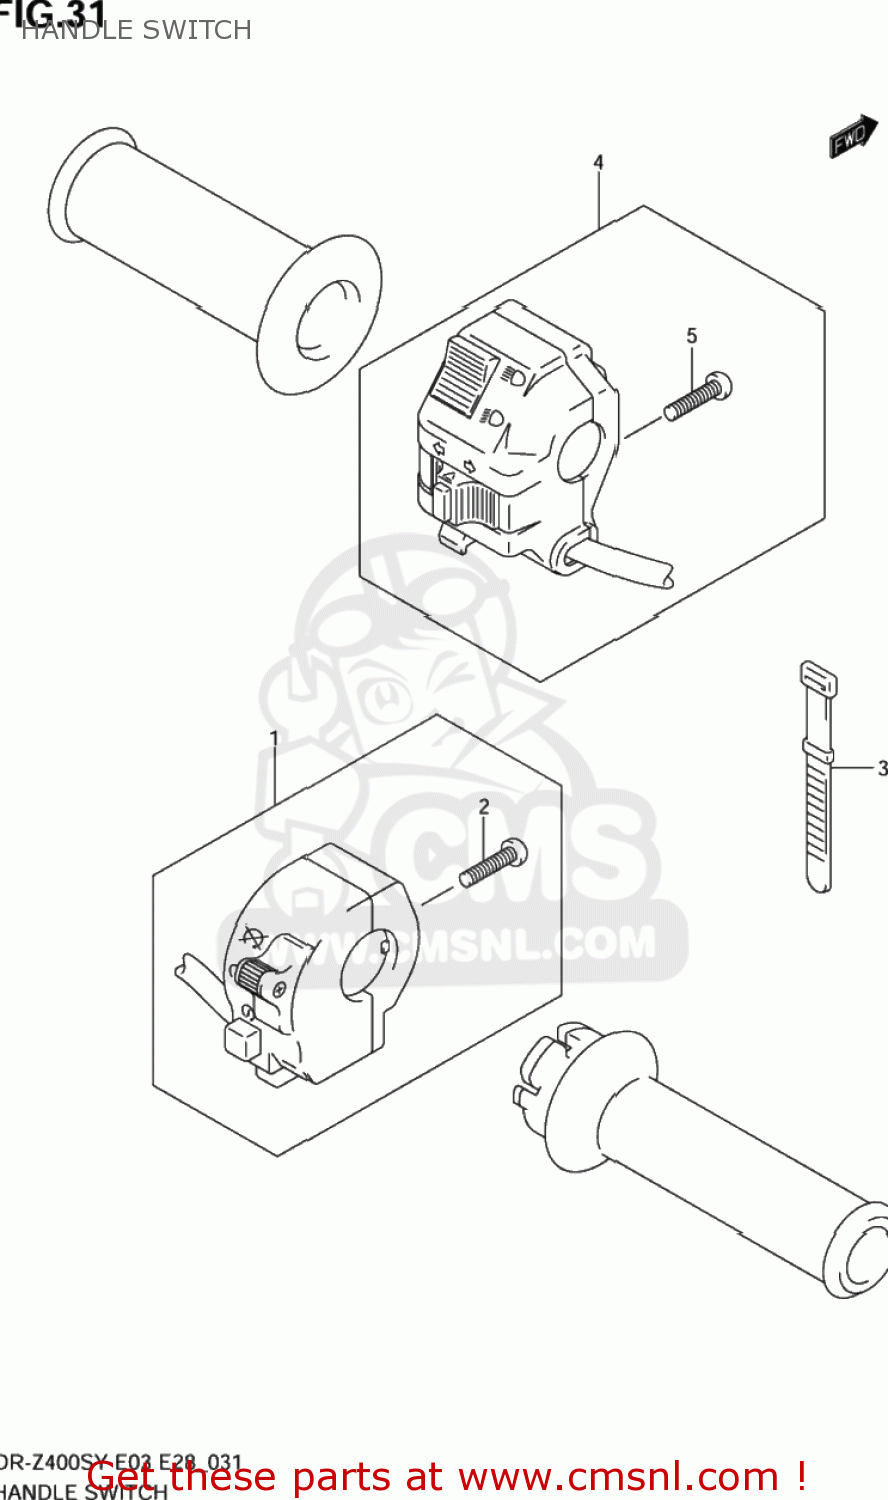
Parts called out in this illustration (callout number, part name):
1	SWITCH ASSY,HANDLE,R
2	SCREW
3	CLAMP(L:120)
4	SWITCH ASSY,HANDLE,L
5	SCREW
